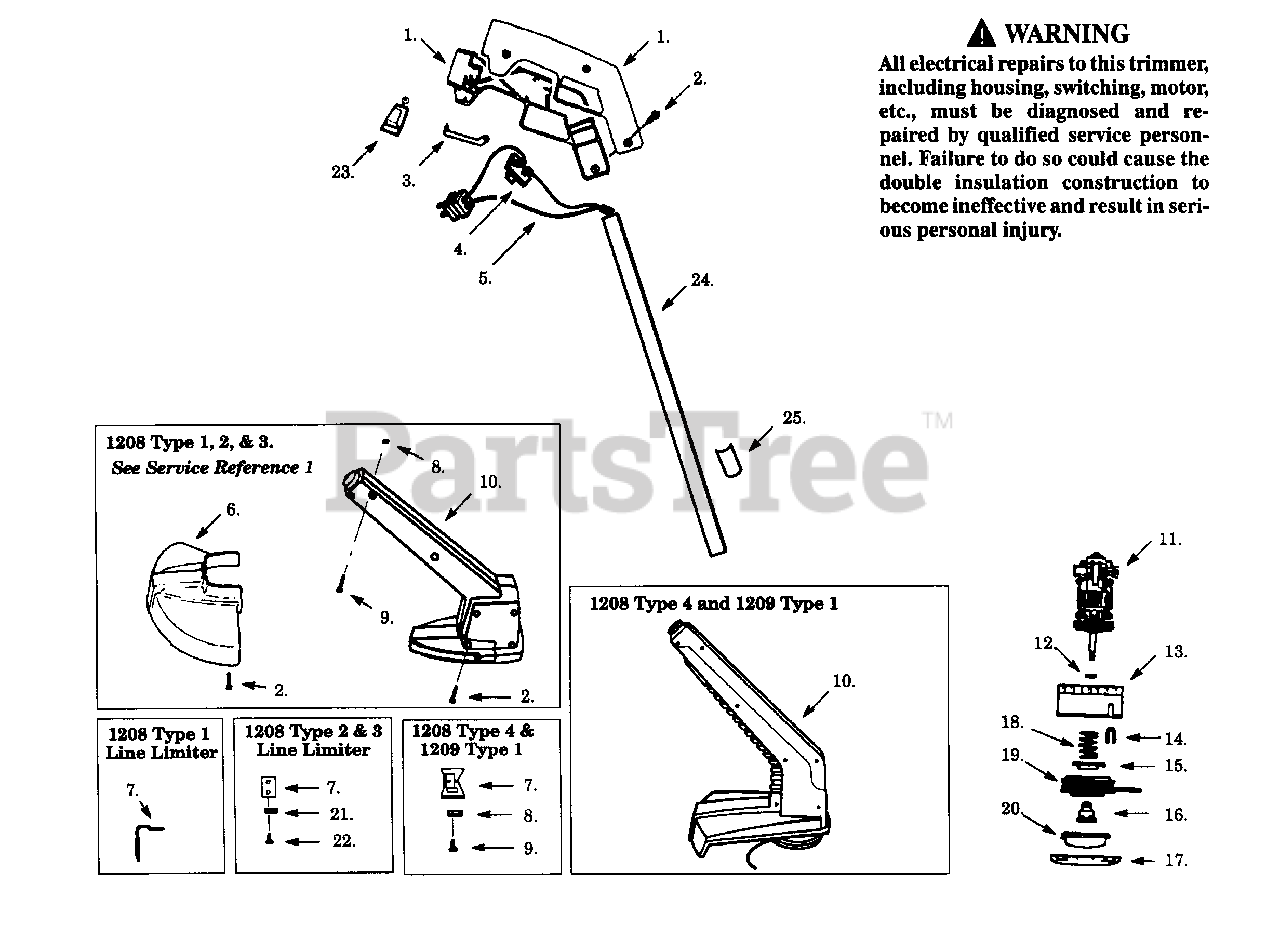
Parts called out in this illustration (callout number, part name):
1	Handle Set
4	On/Off Switch
5	Wiring Harness
6	Shield, 1208 Type 2 & 3
7	Line Limiter, 1208 Type 1
7	Line Limiter, 1208 Type 2 & 3
7	Line Limiter, 1208 Type 4
7	Line Limiter, 1209 Type 1
10	Motor Housing Set, 1208 Type 2
10	Motor Housing Set, 1208 Type 3
10	Motor Housing Set, 1208 T4 & 1209T1
11	Motor Assembly, 1208 Type 1 & 2
11	Motor Assembly, 1208 Type 3 & 4, 1209 Type 1
14	Line Saver
15	Spring Cap
16	Drive Gear
19	Spool
20	Tap Button
21	Blade Cover
23	Cord Retainer
24	Tube w/decal
25	Warning Decal
